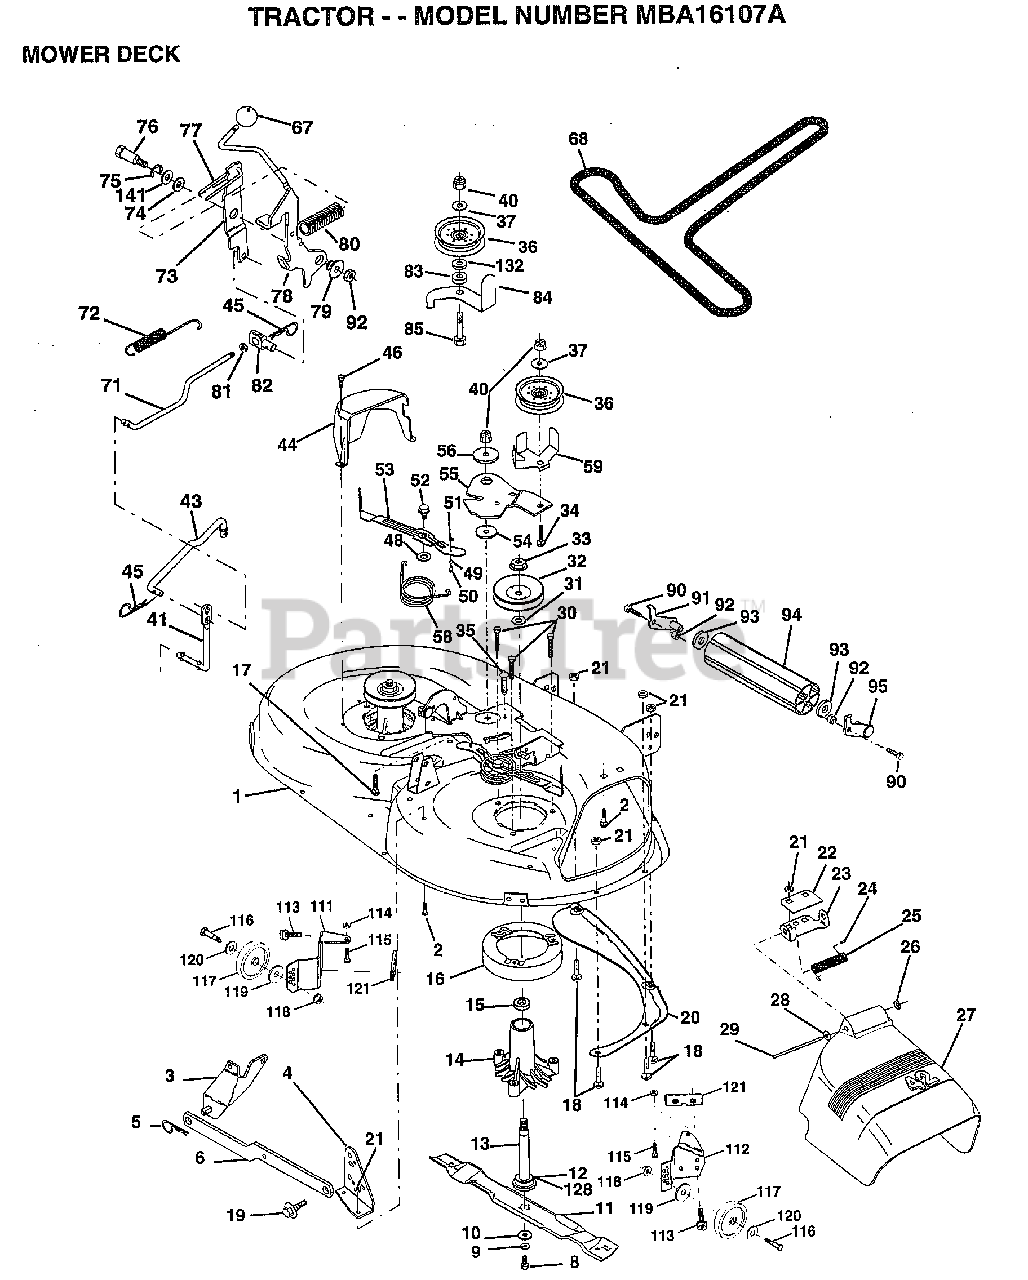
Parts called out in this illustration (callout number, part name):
1	"HOUSING ASSY.42"""
2	BOLT
3	BRKT ASM SWAY BAR
4	BRKT DECK SW BAR
8	BLADE BOLT
10	WASHER.HARD.BLADE
11	"BLADE.42"" HIPERF"
12	BEARING.BALL
14	HSG ASM MANDREL
15	BEARING
16	STRIPPER RND MWR
17	BOLT RDHD 3/8-16
18	BOLT
19	BOLT SHD 5/16-18
20	BAFFLE VORTEX 42
22	STIFFENER BRKT
23	DEFLECTOR BRKT
24	CAP-SLEEVE LT
25	SPRING TORSION
26	NUT PUSH M
27	DEFLECTOR.SHIELD
28	WASHER
29	HINGE ROD
30	"SCREW-THD ROLL,WA"
31	WASHER
32	PULLEY.MANDREL.42
34	BOLT
35	XMAS TREE FASTNER
36	FLAT IDLER PULLEY
37	WASHER
40	NUT
41	PIVOT ROD
43	ROD CLUTCH W/NIBS
44	GUARD MAND LH BLK
45	RETAINER M
46	SCREW.1/4-20X5/8
48	HARD SMALL WASHER
49	ROLLER ASM-CAM
50	SHOULDER BOLT
51	LOCKNUT
52	BOLT.SHLD.5/16-18
53	BRAKE PAD ARM ASM
54	HARDENED WASHER
55	ARM-IDLER
56	SPACER RETAINER
58	SPRING TORSN BRAK
59	GUARD IDLER TUV
67	KNOB.RD.7/16-14
68	BELT.V.T-PATH
71	ROD CLUTCH 38/42
72	RETURN SPRING
73	CLUTCH ARM SECOND
74	WASHER
75	RING
76	SHOULDER BOLT
77	SPRING KEEPER
78	LEVER.ASM.CLUTCH
79	BUSHING
80	SPRING.CLUTCH.MWR
81	NUT
82	TRUNION ADJ
83	WASHER
84	"KEEPER-BELT,FIXED"
85	BOLT
90	BOLT
92	NUT
93	WASHER
111	BRACKET.GWHL.LH.
112	BRACKET.GWHL.RH.
113	SCREW
116	BOLT.SHOULDER
117	WHEEL.GAGE.BLK.PL
118	LOCKNUT
119	WASHER
120	WASHER
121	BRACKET.EXTRD.GWL
128	WASHER.FELT.
129	WASHER
130	BOLT
132	WASHER GT
141	WASHER .T
